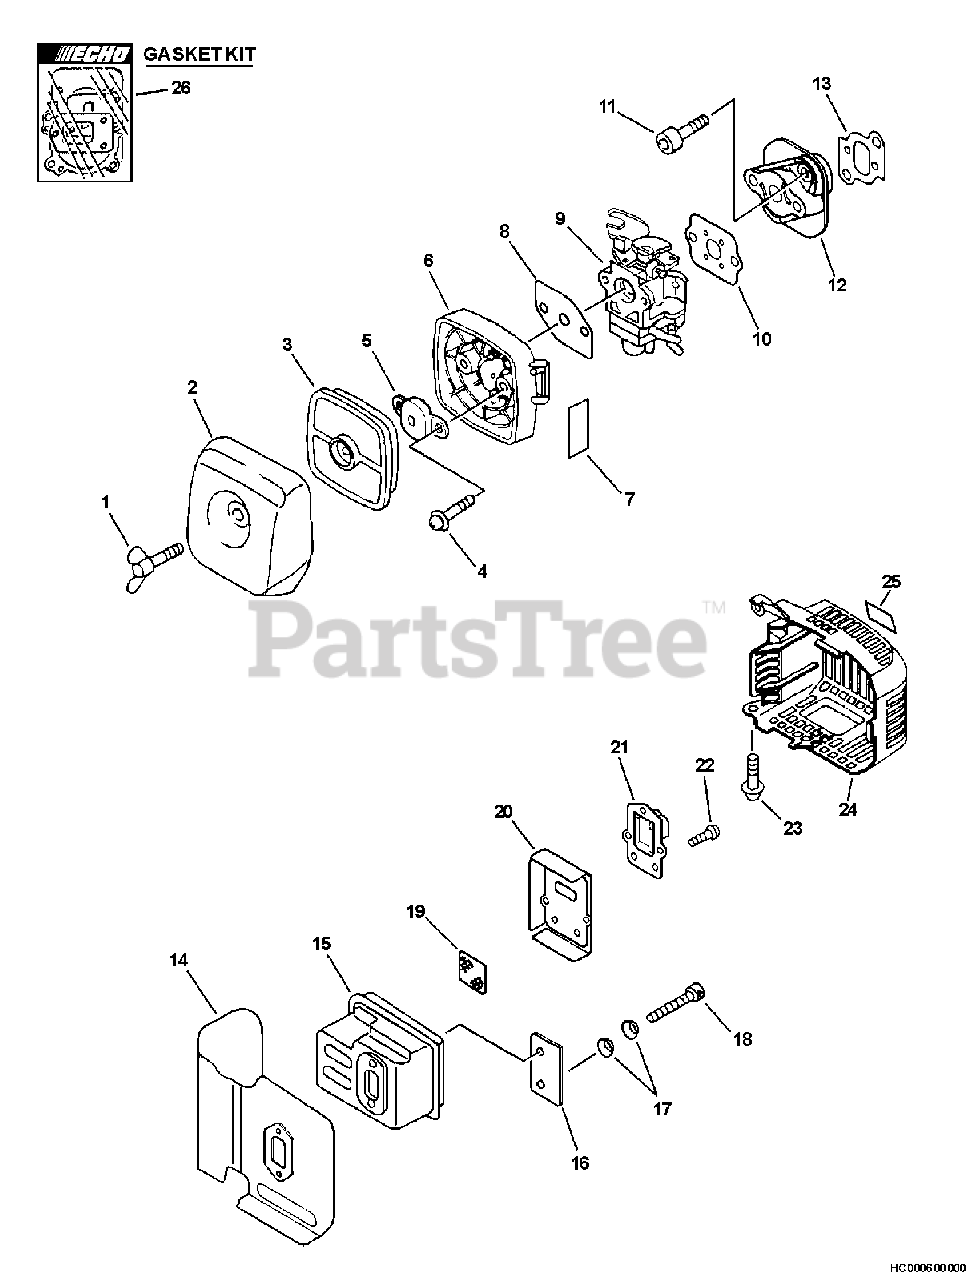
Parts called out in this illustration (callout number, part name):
1	THUMBSCREW
2	COVER, AIR FILTER - GRAY
3	FILTER, AIR - SINGLE LAYER
4	SCREW - 5X60
5	PLATE, PREVENT
6	CASE, AIR FILTER - GRAY
7	LABEL - CHOKE
8	GASKET, INTAKE
9	CARBURETOR WYJ-258
10	GASKET, INTAKE
11	SCREW - 5X25
12	INSULATOR, INTAKE
13	GASKET, INTAKE
14	SHIELD, EXHAUST
15	MUFFLER
17	WASHER - CONICAL
18	SCREW - 5X55
19	SCREEN, SPARK ARRESTOR
20	GASKET, EXHAUST
21	GUIDE, EXHAUST
22	SCREW - 4X10
23	SCREW - 5X12
24	COVER, EXHAUST
25	LABEL - HOT SURFACE
26	GASKET KIT
